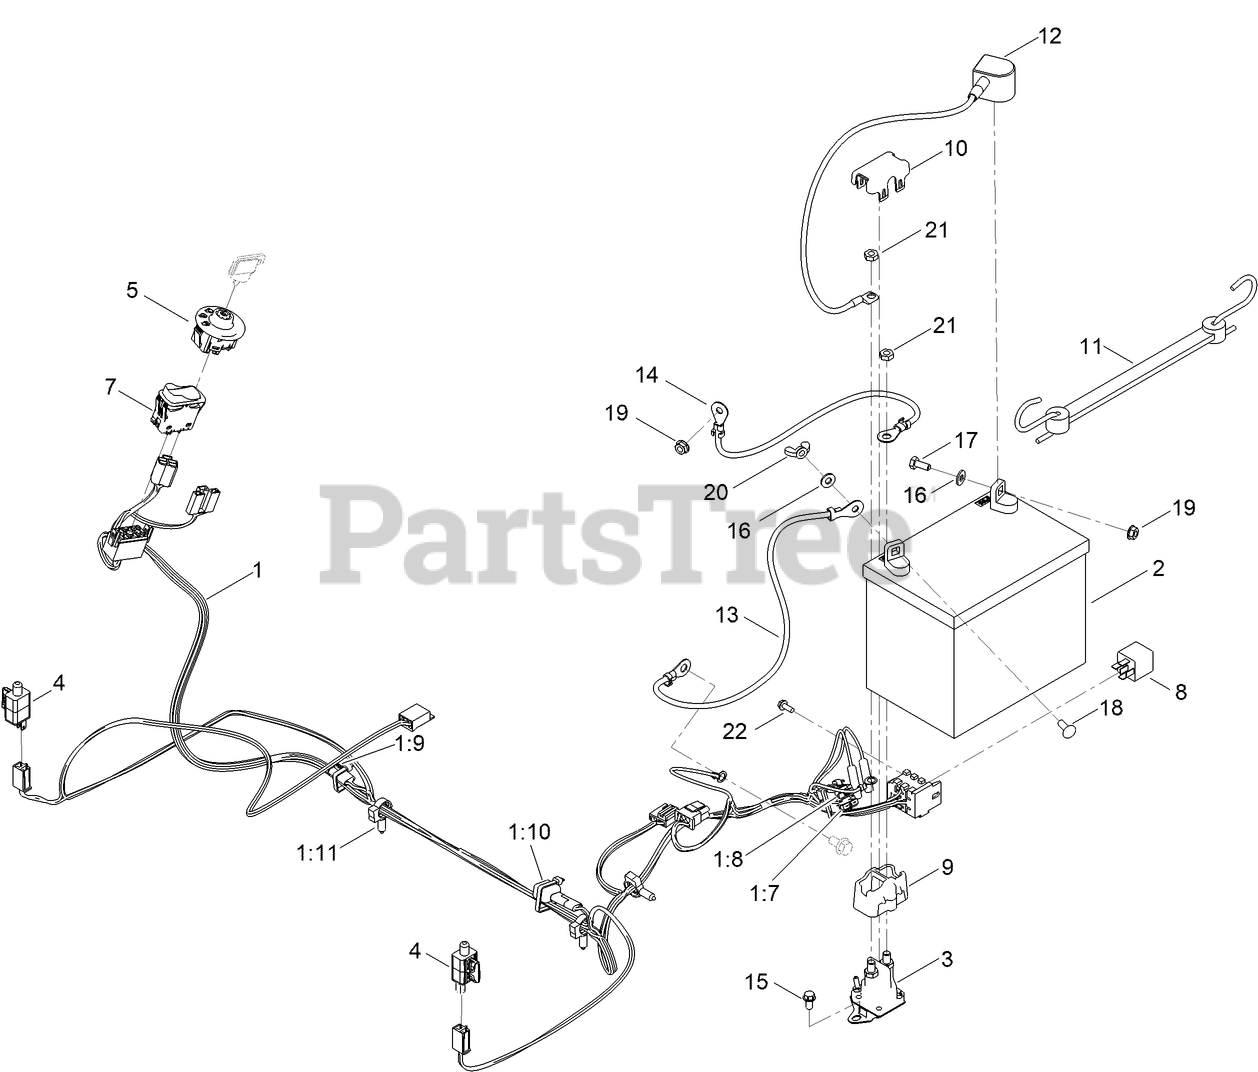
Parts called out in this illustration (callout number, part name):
1	HARNESS-WIRE, MAIN
1:7	FUSE-BLADE, 15 AMP
1:8	FUSE-BLADE, 25 AMP
1:9	CAP-OVER MOLD, 1M/1F
1:11	CLIP-TUBING, HARNESS
3	SOLENOID
4	SWITCH
5	SWITCH-IGNITION
7	SWITCH-ROCKER, ON-NONE-ON
9	COVER-SOLENOID
10	CAP-SOLENOID
11	HOLDDOWN-BATTERY
12	CABLE-BATTERY,RED
13	CABLE-BATTERY, BLACK
14	CABLE-BATTERY, POSITIVE
15	SCREW-HWH
16	WASHER-FLAT
17	SCREW-HH
18	BOLT-CARR
19	NUT-HF
20	NUT-WING
21	NUT-JAM
22	SCREW-TAPTITE
